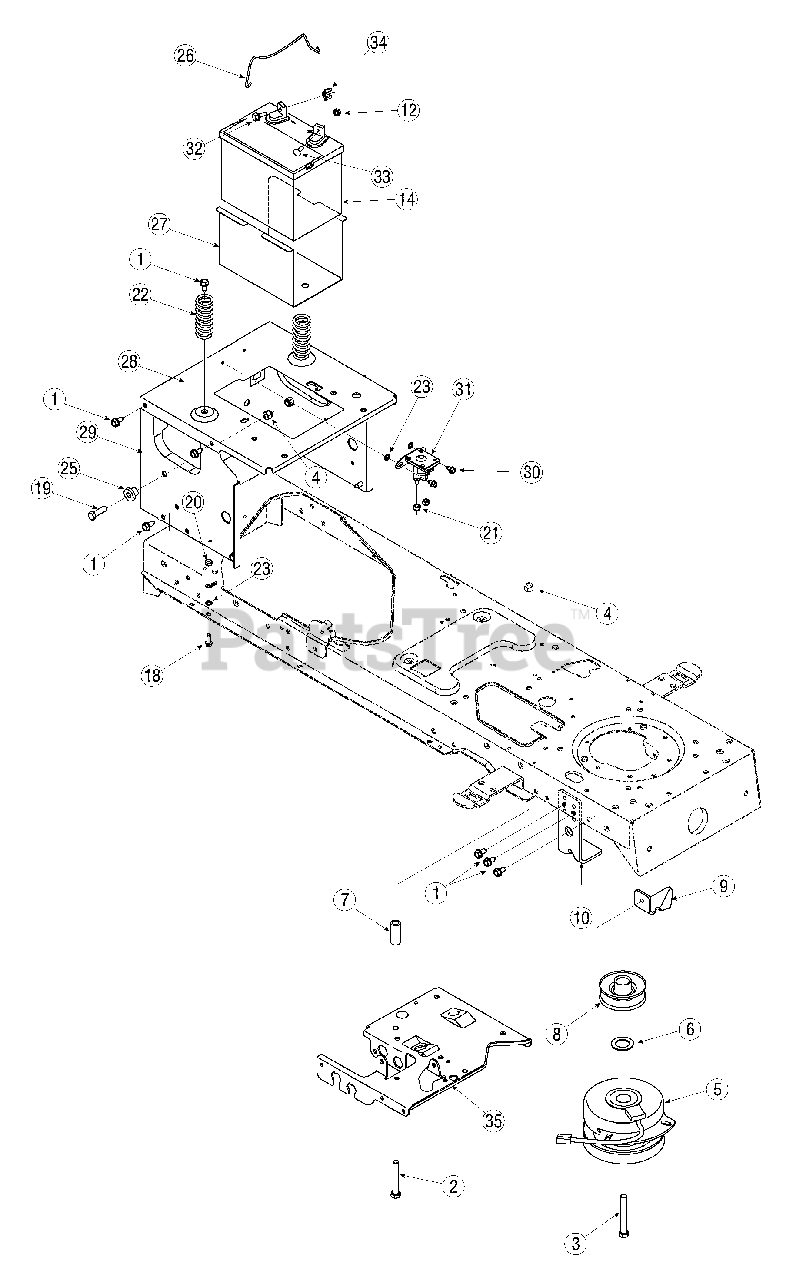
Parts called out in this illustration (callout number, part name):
1	Screw, 5/16-12, 0.75
2	Screw, 3/8-16, 2.50, Gr5
3	Screw, 7/16-20, 3.25, Gr5, Lock
4	Nut, Flange Lock, 3/8-16, Gr F, Nylon
5	PTO Clutch, Electric
6	Washer, Flat, 1.031 x 1.620 x.095
7	Spacer,.385 ID x.635 OD x 1.54
8	Pulley, Engine
11	Screw, Carriage, 1/4-20,.75, Gr5
12	Nut, Sems, 1/4-20
13	Nut, Wing, 1/4-20
14	Battery, 235 CCA
15	Screw, Shoulder,.250 x.150, 1/4-20
18	Screw, 1/4-20, 0.750
19	Screw, 3/8-16, 1.25, Gr5
20	Nut, Flange Lock, 1/4-20, Gr F, Nylon
21	Nut, Hex, 1/4-20, Gr5
22	Spring, Compression, 1.28 OD x 3.125
23	Washer, Lock, 1/4, External
24	Washer, Lock, 1/4
25	Spacer, Shoulder,.38 x 1.0 x.70
26	Hold Rod, Battery
30	Screw, 1/4-20, 0.50
31	Solenoid, 12V, 100 Amp
32	Screw, Shoulder,.250 x.15, 1/4-20
33	Screw, Carriage, 1/4-20,.75
34	Nut, Wing, 1/4-20
